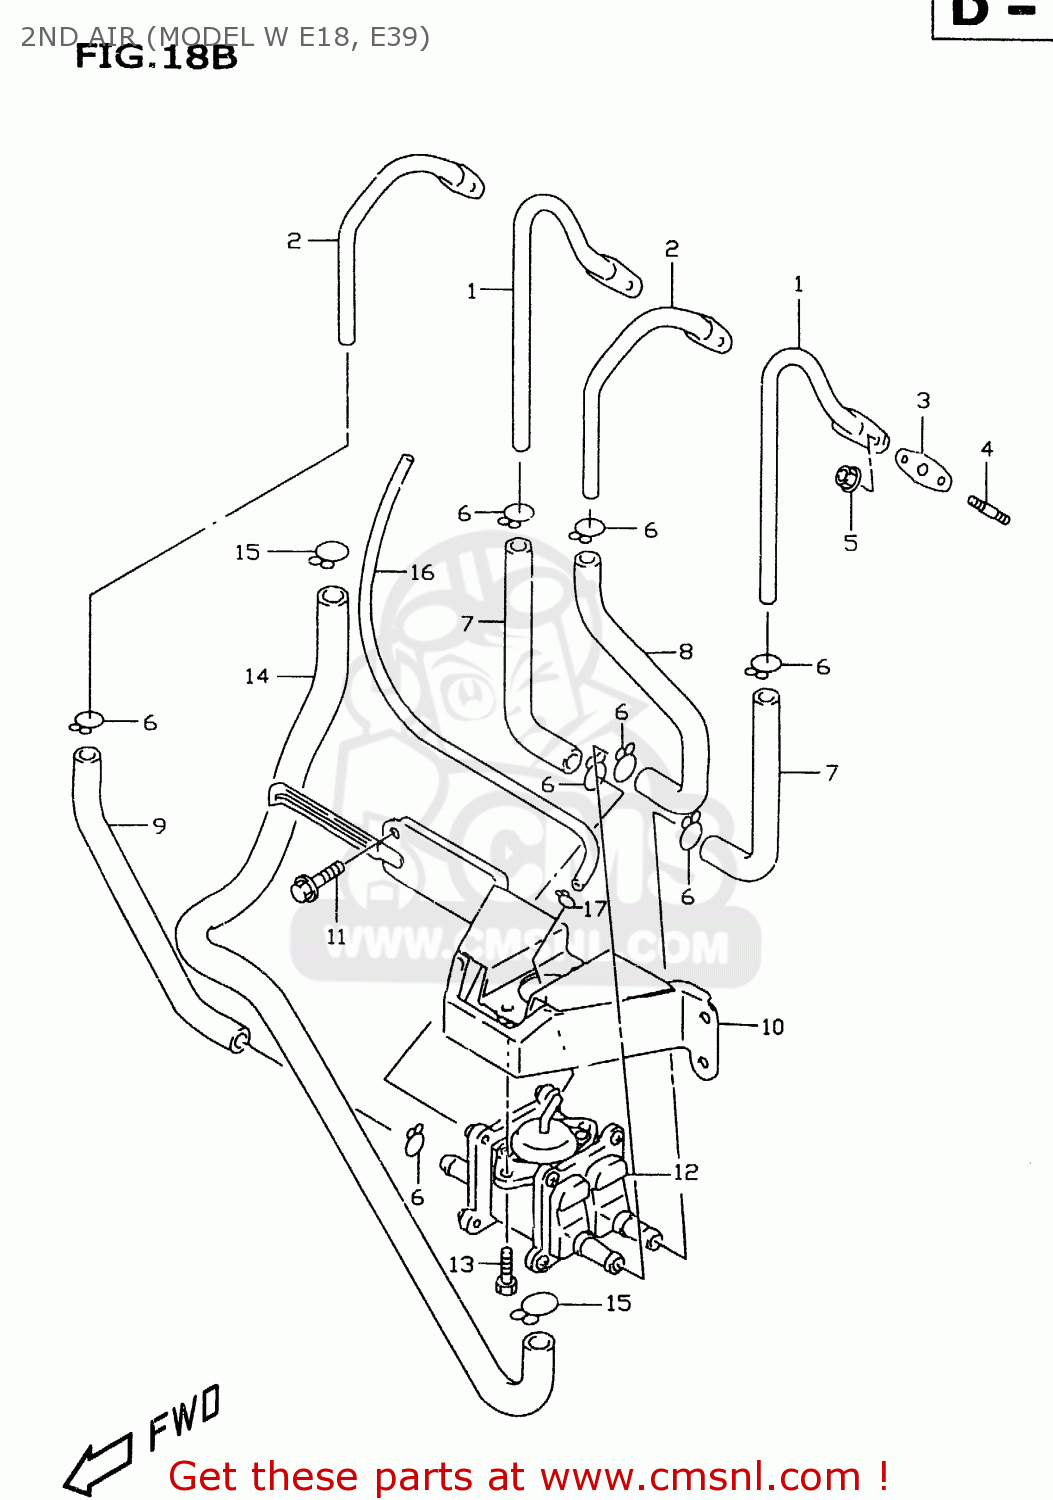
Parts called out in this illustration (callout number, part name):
1	PIPE COMP,SECOND AIR NO.1
2	PIPE COMP,SECOND AIR NO.2
3	GASKET,SECOND AIR PIPE (N (NAS)
4	STUD BOLT
5	NUT
6	CLIP
7	HOSE,2ND AIR VALVE NO.1
8	HOSE,2ND AIR VALVE NO.2
9	HOSE,2ND AIR VALVE NO.4
10	BRACKET,SECOND AIR VALVE
11	BOLT 6X12
12	VALVE ASSEMBLY,SECOND AIR
13	BOLT,OIL FILLE
14	HOSE,SECOND AIR CLEANER
15	CLIP
16	HOSE(4X7X2000)
17	CLIP
